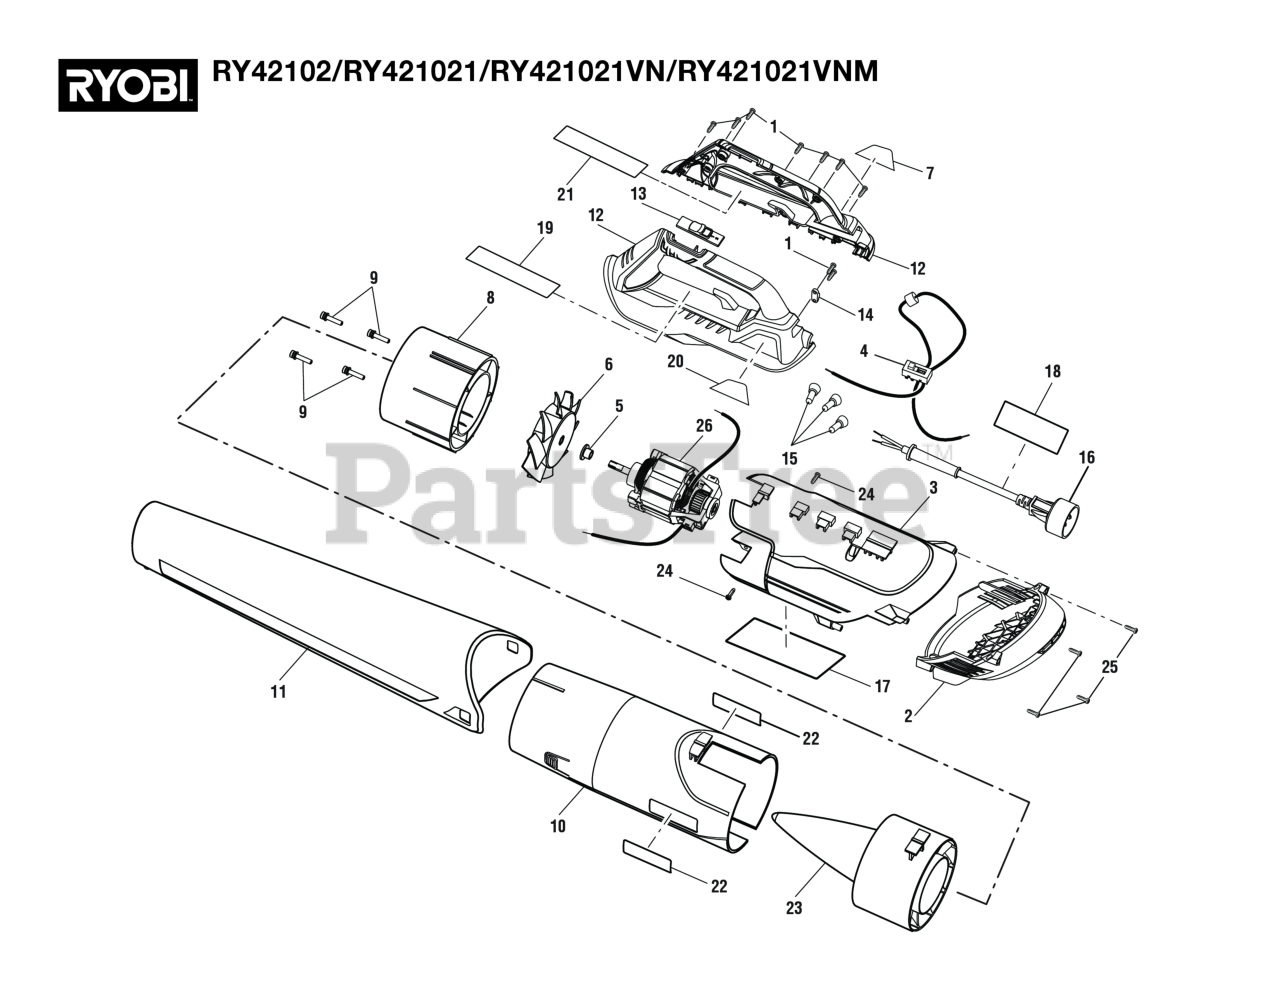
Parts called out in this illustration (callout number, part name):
1	Screw (M4 x 14 mm, T15 Torx Pan Hd.))
2	Inlet Guard
3	Housing Assembly
4	Switch and Fuse Assembly
5	Bushing for motor shaft
6	Fan w/Insert Nut
7	8 Amp Label (Right)
8	Motor Housing Assembly
9	Cap Screw w/Washer (M5 x 16 mm, T25 Torx Soc. Hd.)
10	Outlet Housing Assembly
11	Blower Tube
12	Handle Assembly
13	Switch Trigger
14	Cord Clamp
15	Wire Connector (Closed End)
16	Power Cord Assembly
17	Data Label (RY42102)
18	Warning Label (Fr/Sp)
19	Icon Warning Label
20	8 Amp Label (Left)
21	Warning Label
22	Logo Label
23	Tail Cone
24	Screw (M4 x 16 mm, T15 Torx Pan Hd.)
25	Screw (M4 x 20 mm, T20 Torx Pan Hd.)
26	Motor Assembly
